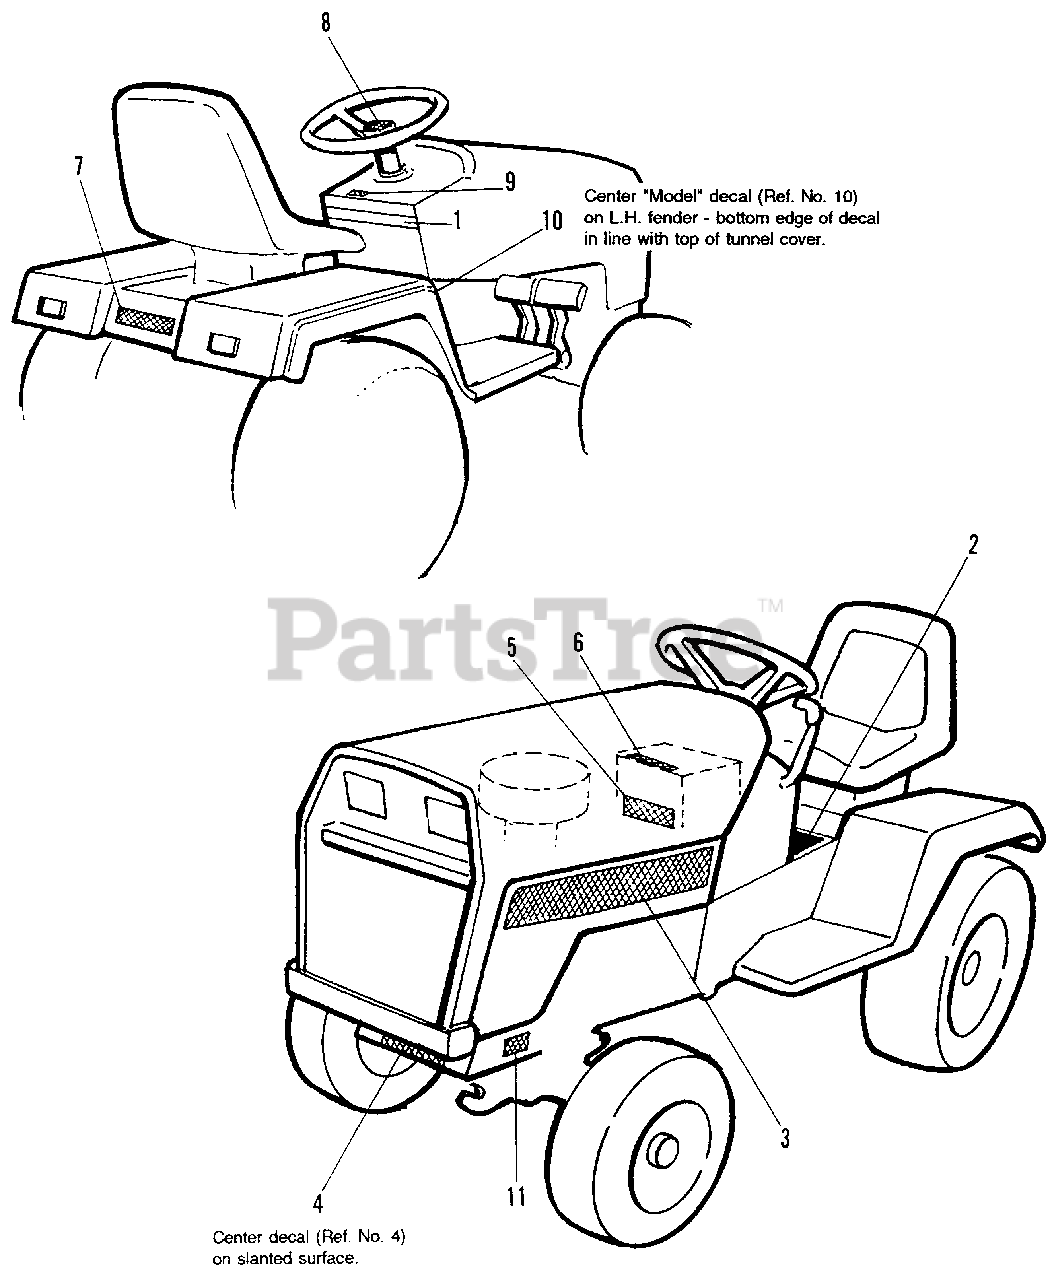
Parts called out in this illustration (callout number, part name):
1	DECAL, Panel, Rear Dash (Choke, Ignition, etc.)
2	DECAL, Tunnel Cover (1691924 only)
2	DECAL, Tunnel Cover (1691926, 1691928, 1681953 only)
3	DECAL, Hood, L.H.
3	DECAL, Hood, R.H.
4	DECAL, Waming, Front PTO Shield
5	DECAL, Battery
6	DECAL, Warning (Disconnect Elect. Ground, etc.)
7	DECAL, Rear Logo
8	DECAL, Steering Wheel Cap
9	DECAL, Rear PTO (1691928 only)
10	DECAL, Model 18GTH
10	DECAL, Model 20GTH
11	I.D. PLATE
